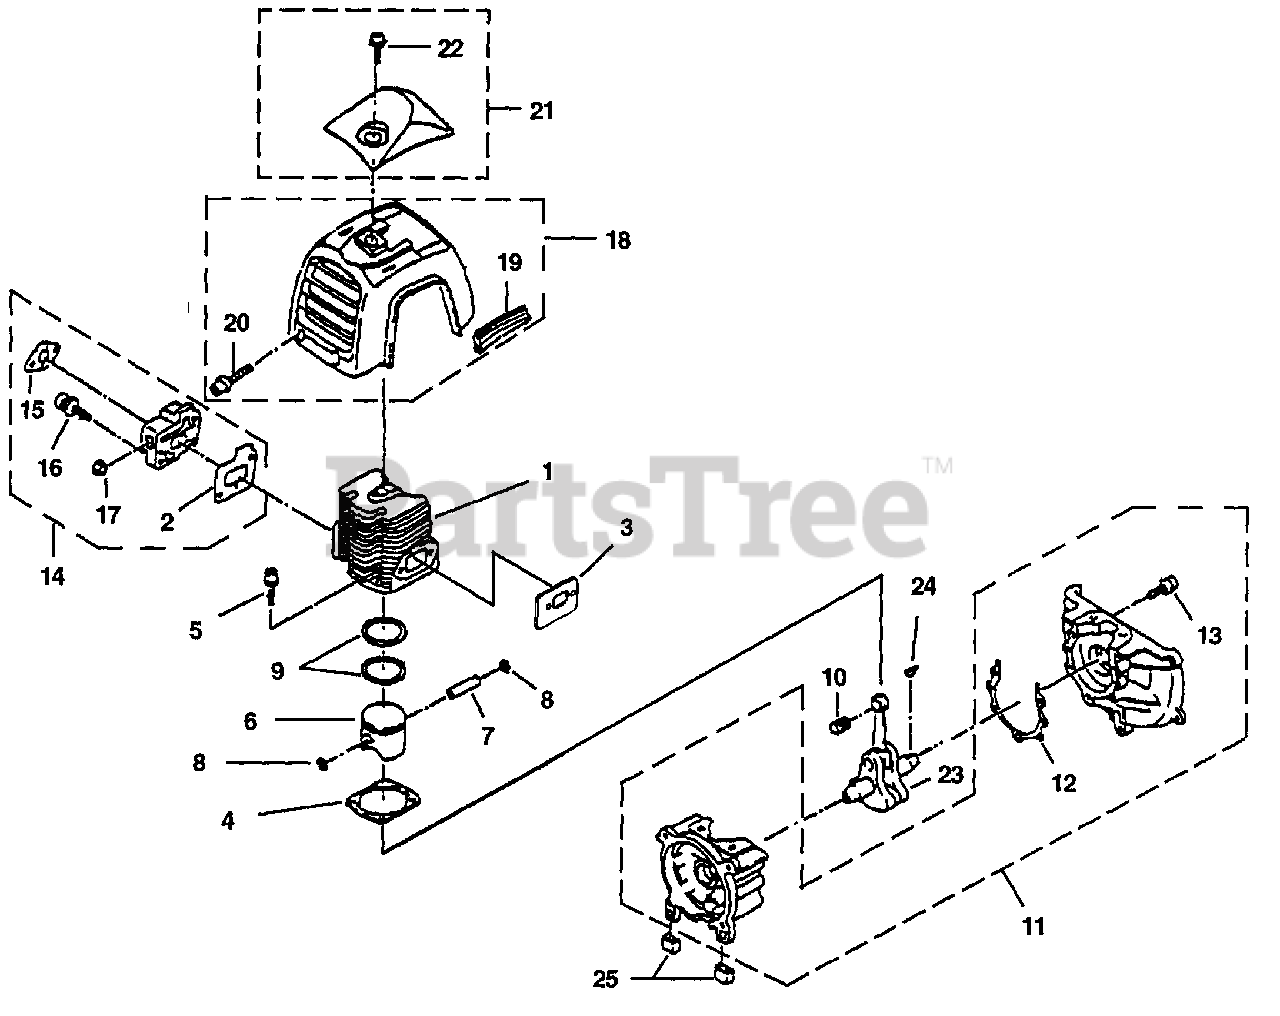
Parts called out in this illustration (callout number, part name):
1	CYLINDER ASSEMBLY
2	GASKET-Heat Dam
3	GASKET-Muffler
4	GASKET-Cylinder
5	SCREW-Socket HD (M5 x 18 SW)
6	PISTON ASSEMBLY
7	PIN-Piston
8	RING-Retaining
9	RINGS-Piston
10	BEARING-Wrist Pin
11	CRANKCASE ASSEMBLY
12	GASKET-Crankcase
14	HEAT DAM ASSEMBLY
15	GASKET-Carburetor
16	SCREW-Socket Hd (M5 x 20)
18	CYLINDER COVER
19	BUMPER, Rubber
20	SCREW (M5 x 30)
21	PLUG COVER
23	CRANKSHAFT
24	KEY-Woodruff
25	BUMPER, Rubber
